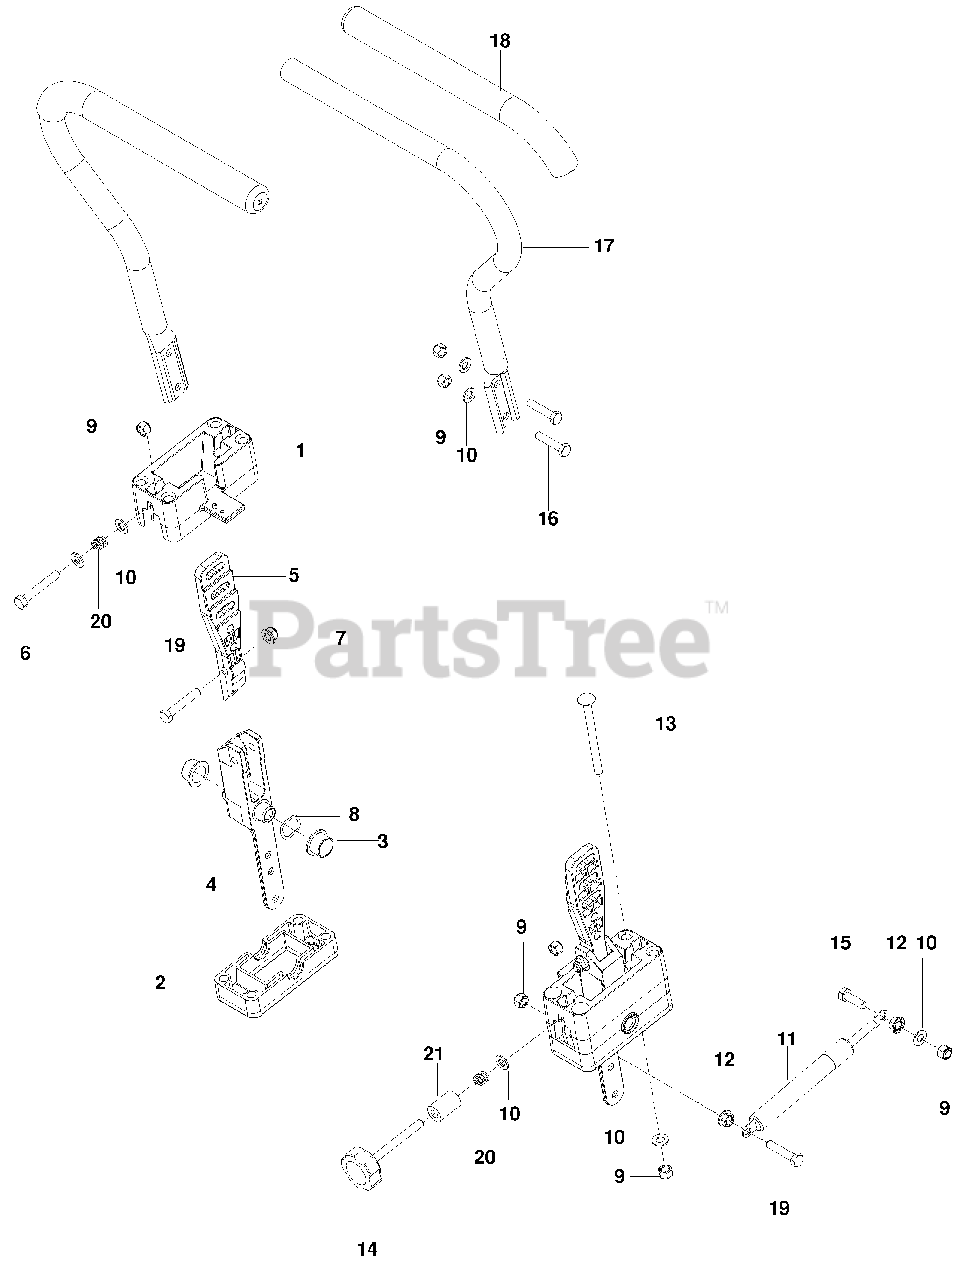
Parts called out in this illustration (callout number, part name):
1	BLOCK, UPPER
2	BLOCK, LOWER
3	BEARING, FLANGE
4	PIVOT SECTION, DRIVE
5	MOUNT, DRIVE CONTROL
6	HCS 5/16-18 x 2
7	NUT 5/16-18 FLANGE NYLOC
8	WASHER, WAVE
9	NUT 5/16-18 HEX NYLOC
10	WASHER 5/16 SAE FLT
12	NUT 5/16-18 HEX WHIZLK
13	RHSNB 5/16-18 x 4
15	HCS 5/16-18 x 1
16	HCS 5/16-18 x 1 1/2
17	LEVER, w/ GRIP
18	GRIP, FOAM
19	HCS 5/16-18 x 1 3/4
